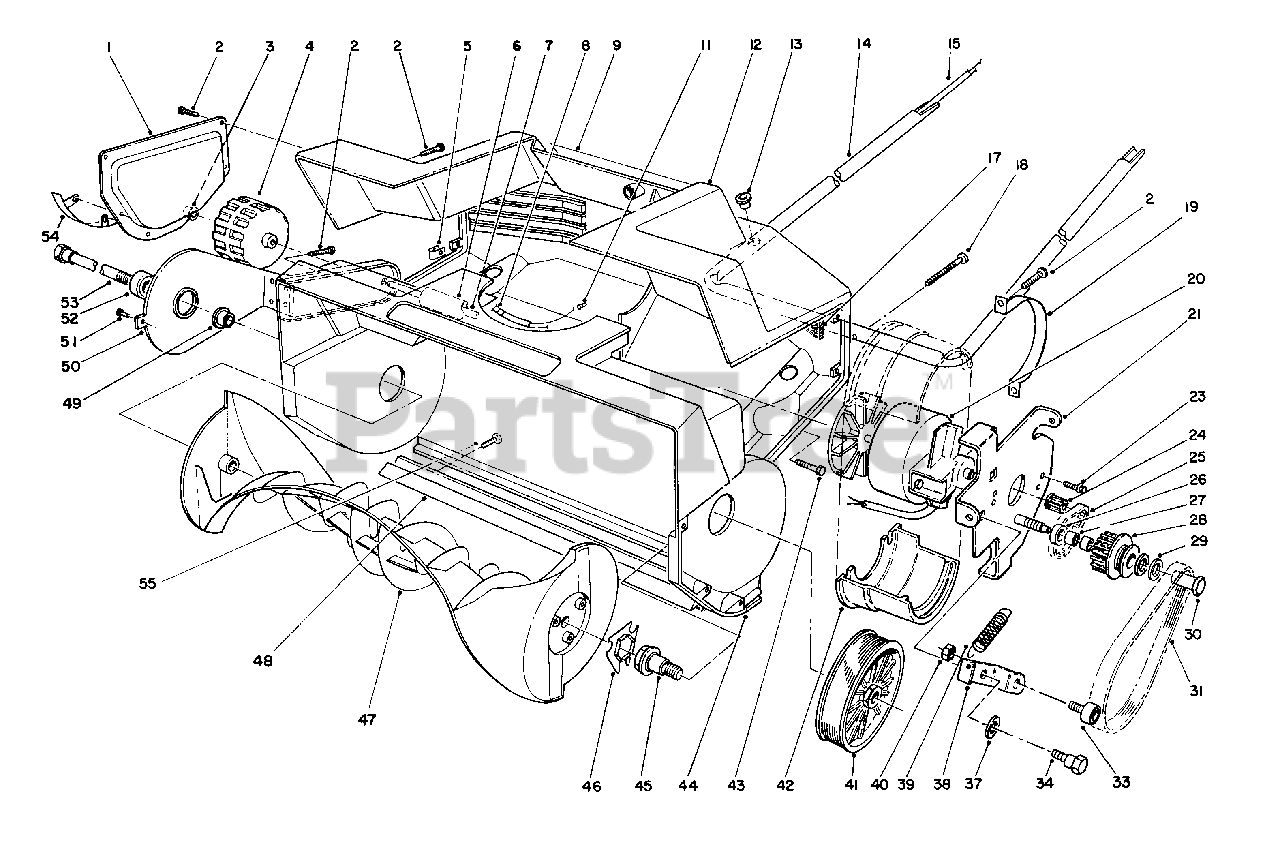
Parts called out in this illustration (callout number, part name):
1	Plate-Side
2	Screw-Pan Hd.
3	Push Nut
5	U-Clip-Tinnerman
6	Sleeve-Axle
7	Shaft-Axle
8	Relief-Strain
9	Decal-Danger
11	Connector
12	Shroud-Housing
14	Tube-Lower Handle
15	Wire Harness
17	Filter-Foam
18	Screw-Pan Hd.
19	Strap-Motor
21	Motor Plate Assembly
23	Screw-Hex. Washer Hd.
24	Pulley-Driver
25	Belt-Timing
27	Bearing-Needle
28	PulleyAssembly-Idler (Incl. Ref. #27)
29	Washer-Thrust
30	Bolt-Idler
31	Belt-Drive
33	Bearing Assembly (Incl. Ref. #40)
34	Screw-Shoulder
38	Bracket-Idler
40	Nut-Lock
41	Pulley-Driven
42	Clamp-Motor Bracket
43	Screw-Hex. Hd.
44	Housing-Rotor
45	Shaft-Rotor Driver
46	Coupler-Rotor
50	Bracket-Wheel (Incl. Ref. #52)
51	Rivet-Pop
52	Bearing-Ball
53	Shaft-Rotor
54	Skid-Housing
55	Screw-Pan Hd.
